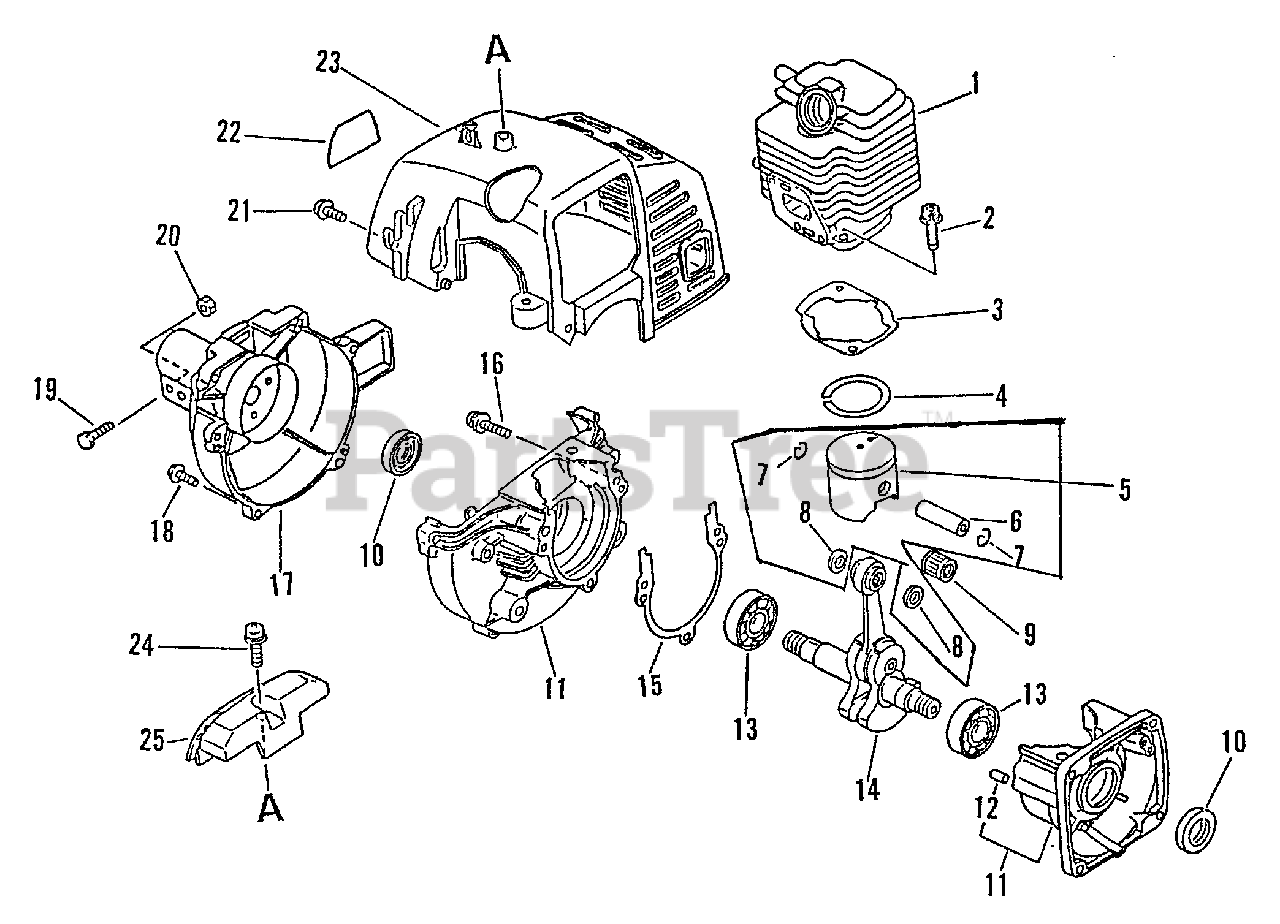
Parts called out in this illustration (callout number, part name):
2	BOLT 5×22
3	GASKET, CYLINDER
4	RING, PISTON
5	PISTON KIT
6	PIN, PISTON 8
7	RING, SNAP
8	WASHER, THRUST
9	BEARING, NEEDLE
10	SEAL, OIL 12
11	CRANKCASE KIT
12	PIN, LOCATING 4
13	BEARING, BALL - 6201 C3
14	CRANKSHAFT ASSY
15	GASKET, CRANKCASE
16	SCREW 5×28
17	FAN CASE ASSY
18	SCREW 5×18
19	BOLT 5×28
20	NUT M5
21	SCREW 4×12
22	LABEL - MODEL
23	COVER, ENGINE - GRAY
24	SCREW - 5×16
25	GUARD, TOP - BLACK
